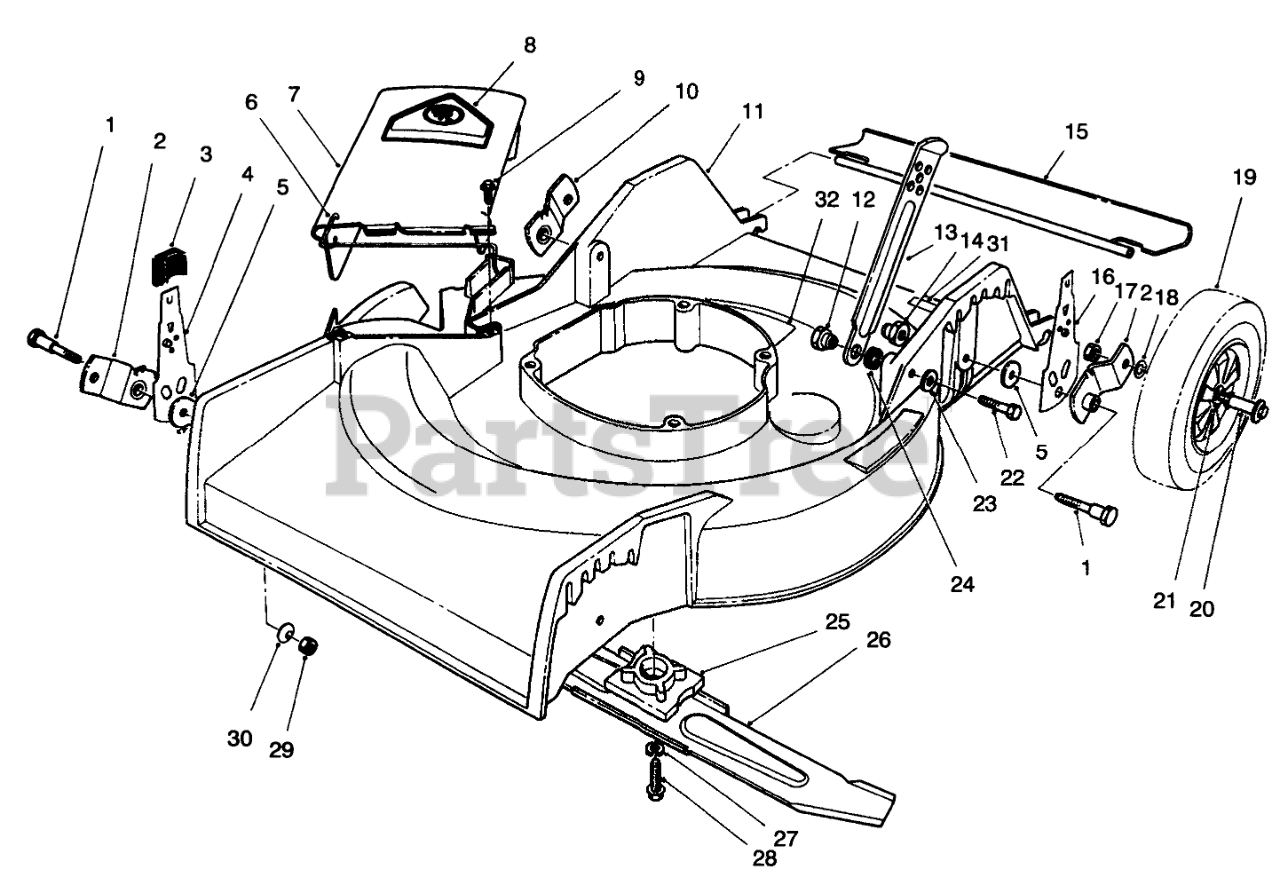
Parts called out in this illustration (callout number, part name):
1	5/16-18 PIVOT SCREW
2	Pivot Arm
3	KNOB-ARM
4	RH FRONT SPRING ARM ASM
5	PIVOT WASHER
6	SPRING HINGE
7	Deflector (Incl. Ref. #6 & 8)
8	DECAL-DANGER
9	SCREW-HWH
10	Pivot Arm
11	Housing (Incl. Ref. #31-32)
12	HANDLE PIVOT NUT
13	Latch-Handle
14	HANDLE PIVOT NUT
15	SHIELD - TRAILING
16	REAR SPRING ARM ASM
17	NUT-LOCK
18	WASHER
19	Wheel & Tire Assembly (Incl. Ref. #21)
20	WHEEL BOLT
21	BUSHING
22	SCREW-HH
23	WASHER-LOCK
24	SPACER
25	BLADE RETAINER
26	Blade
27	WASHER-LOCK
28	SCREW-HH
29	NUT-LOCK, NI
30	WASHER-BELLEVILLE
31	DECAL-WARNING
32	DECAL-INSTRUCTION, SAFETY
